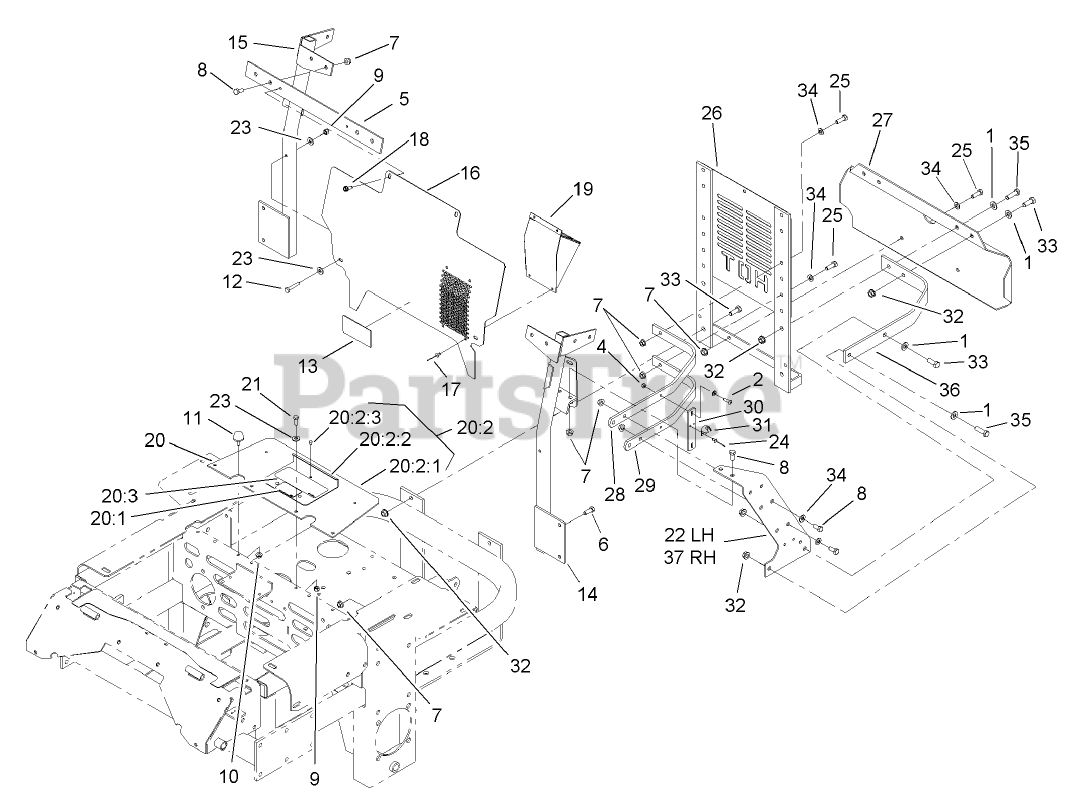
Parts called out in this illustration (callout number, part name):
1	WASHER-FLAT
2	SCREW-HEAD, TRUSS
4	NUT-LOCK, NI
5	CROSSBAR
6	SCREW-HH
7	NUT-HF
8	SCREW-HH
9	NUT-LOCK, NI
10	NUT-HF
11	BUMPER
12	SCREW-HH
13	DECAL-ROUTING, BELT
14	Brace-Radiator, LH
15	BRACE-RADIATOR, RH
16	Deflector-Air
17	RIVET-POP
18	SCREW-HWHTF
19	Plenum-Intake, Air
20	SHIELD ASM
20:1	DECAL-IMPORTANT
20:2	SHIELD AND LIFT ASM
20:2:1	SHIELD-ENGINE
20:2:2	LIFT-SHIELD
20:2:3	RIVET-POP
20:3	DECAL-DEVICES, ROTATING
21	SCREW-HH
22	PLATE-SIDE, LH
23	WASHER-FLAT
24	RIVET
25	SCREW-HH
26	MOUNT-RADIATOR, REAR
27	GUARD-BUMPER
29	RIB-BOTTOM
30	BAR-HOOK, LATCH
31	KEEPER-LATCH, RUBBER
32	NUT-HHF, WHIZ
33	SCREW-HH
34	WASHER-PLAIN
35	SCREW-HH
36	BAR-RADIATOR MOUNT FRAME
37	PLATE-SIDE, RH
